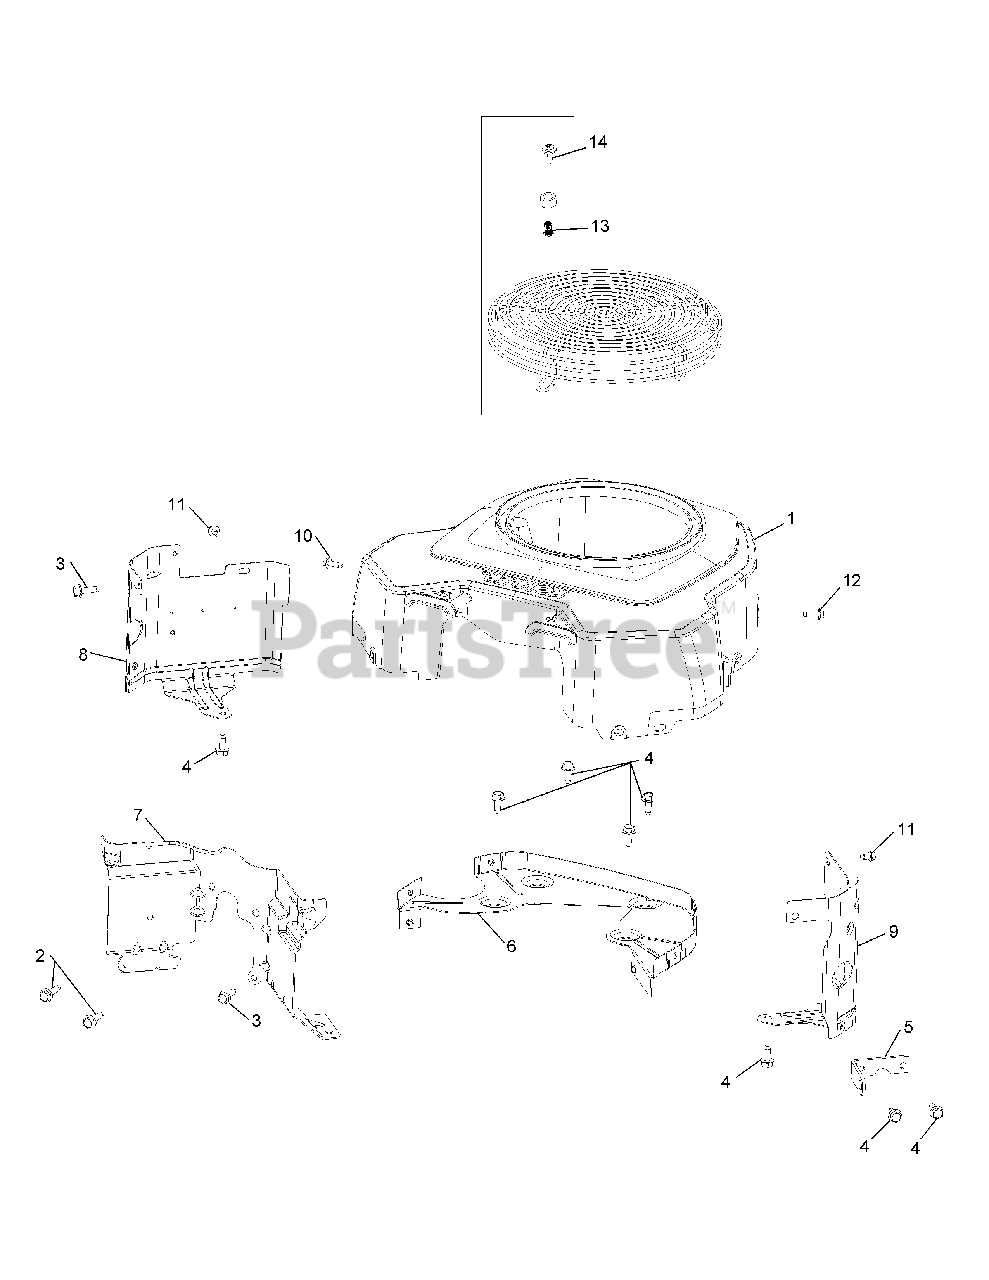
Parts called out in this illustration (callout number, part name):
1	Blower Housing
2	Thread Forming Screw
3	Thread Forming Screw
4	Thread Forming Screw
6	Backing Plate Kit
8	Cylinder Barrel Kit, #1 Side
9	Cylinder Baffle Kit, #2 Side
10	Thread Forming Screw
11	Thread Forming Screw
12	Thread Forming Screw
13	Threaded Insert
